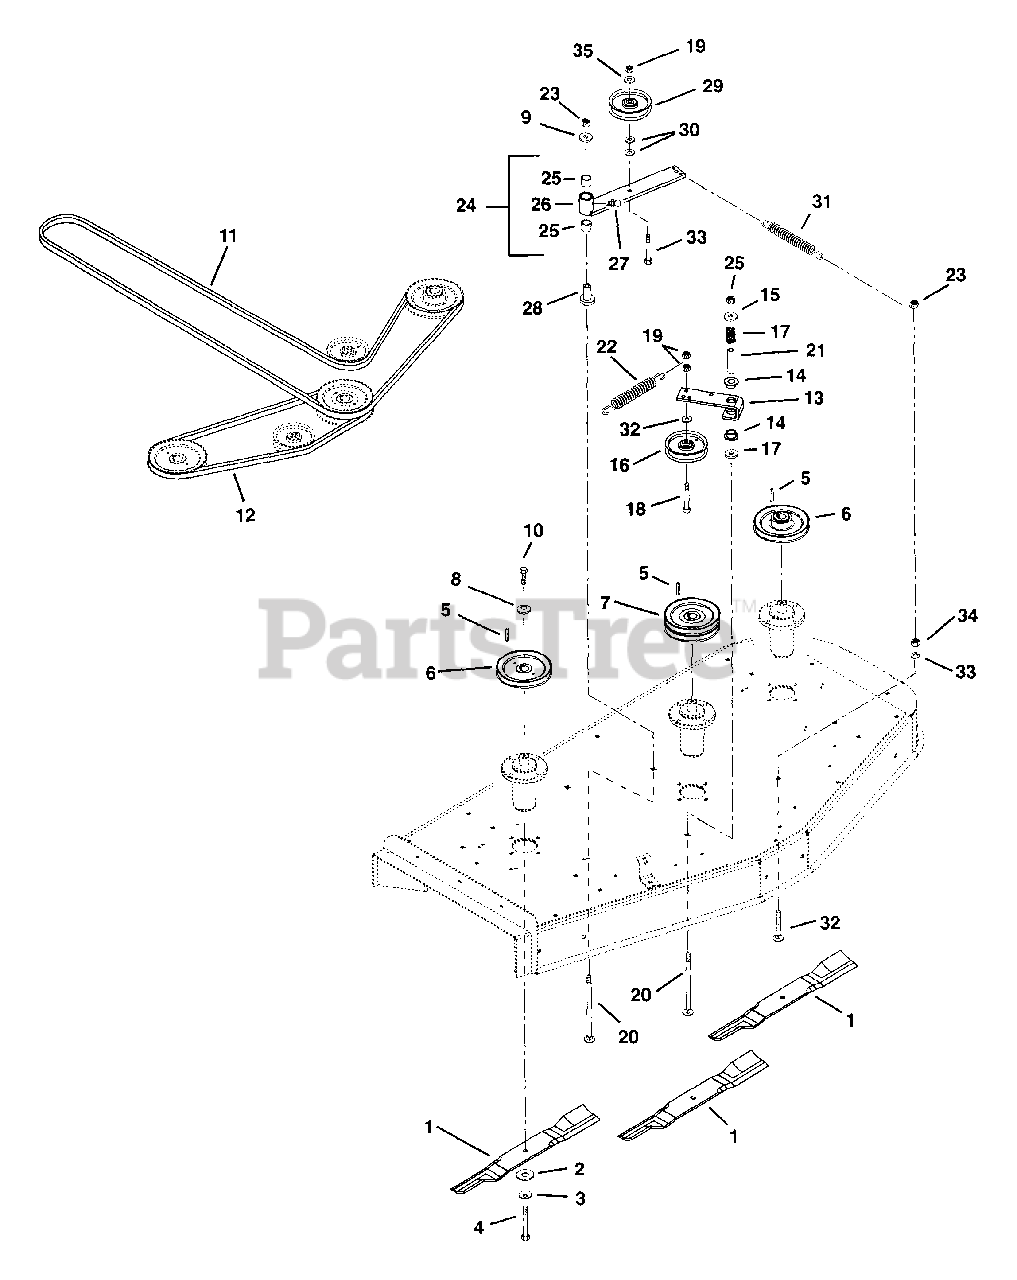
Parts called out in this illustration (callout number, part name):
1	Blade, Mower 60"
1	Blade, 50" Mower Hi-Lift
2	Washer, Flat .640 x 1.81 x .250
3	Washer-Bellville .63 x 1.625 x .14
4	Bolt, Blade
5	Key-Straight .25 x .75 x .25
6	Weldment, Spindle Sheave 6.00 (60" Deck)
6	Weldment, Spindle Sheave 5.00 (50" Deck)
7	Weldment, Spindle Sheave (Double) 6.00 (60" Deck)
7	Weldment, Spindle Sheave-Double 5.00 (50" Deck)
8	Washer, Cupped, Serrated .375
9	Washer-Flat-Steel .531 x 1.250 x .100
10	Bolt-Hex .38-16 x 1.00 Grade 5
11	V-Belt, B-RMA 63.40 x .625 (60" Deck)
11	V-Belt, B-RMA 58.70 x .625 (50" Deck)
12	V-Belt, B-RMA 23.94 x .625 (60" Deck)
12	V-Belt, B-RMA 18.13 x .625 (50" Deck)
13	Arm,Idler Pivot
14	Bushing-Flange .762 x 1.0 x .580 x 1.48 Nylon
15	Washer-Flat-Steel .531 x 1.250 x .100
16	Idler-V 4.00 x .377
17	Spring-Compression .085 x .80 x 1.00 WLD 36
18	Bolt-Hex .38-16 x 2.25 Grade 5
19	Nut-Locking-Center .38-16
20	Bolt-Round Head Square Neck .50-13 x 3.50
21	Spacer .560 x .750 x 2.437 Steel
22	Spring, Extension
23	Nut-Locking-Center .50-13
24	Assembly, Idler Pivot Arm
25	Weldment, Idler Pivot Arm
26	Bearing 1.000 x 1.125 x 1.00
27	Fitting-Lube .25-28 x .256
28	Bearing, Pedestal Powdered Metal
29	Idler-Flat 4.00 x .38
30	Bushing .406 x .750 x .188
31	Spring, Extension
32	Bolt-Round Head Square Neck .50-13 x 1.50 Grade 5 (50" Deck)
32	Bolt-Round Head Square Neck .50-13 x 1.75 Grade 5 (60" Deck)
33	Washer-Locking .50 x .125
34	Nut-Hex .50-13
35	Washer-Flat-Steel .406 x .812 x .065
